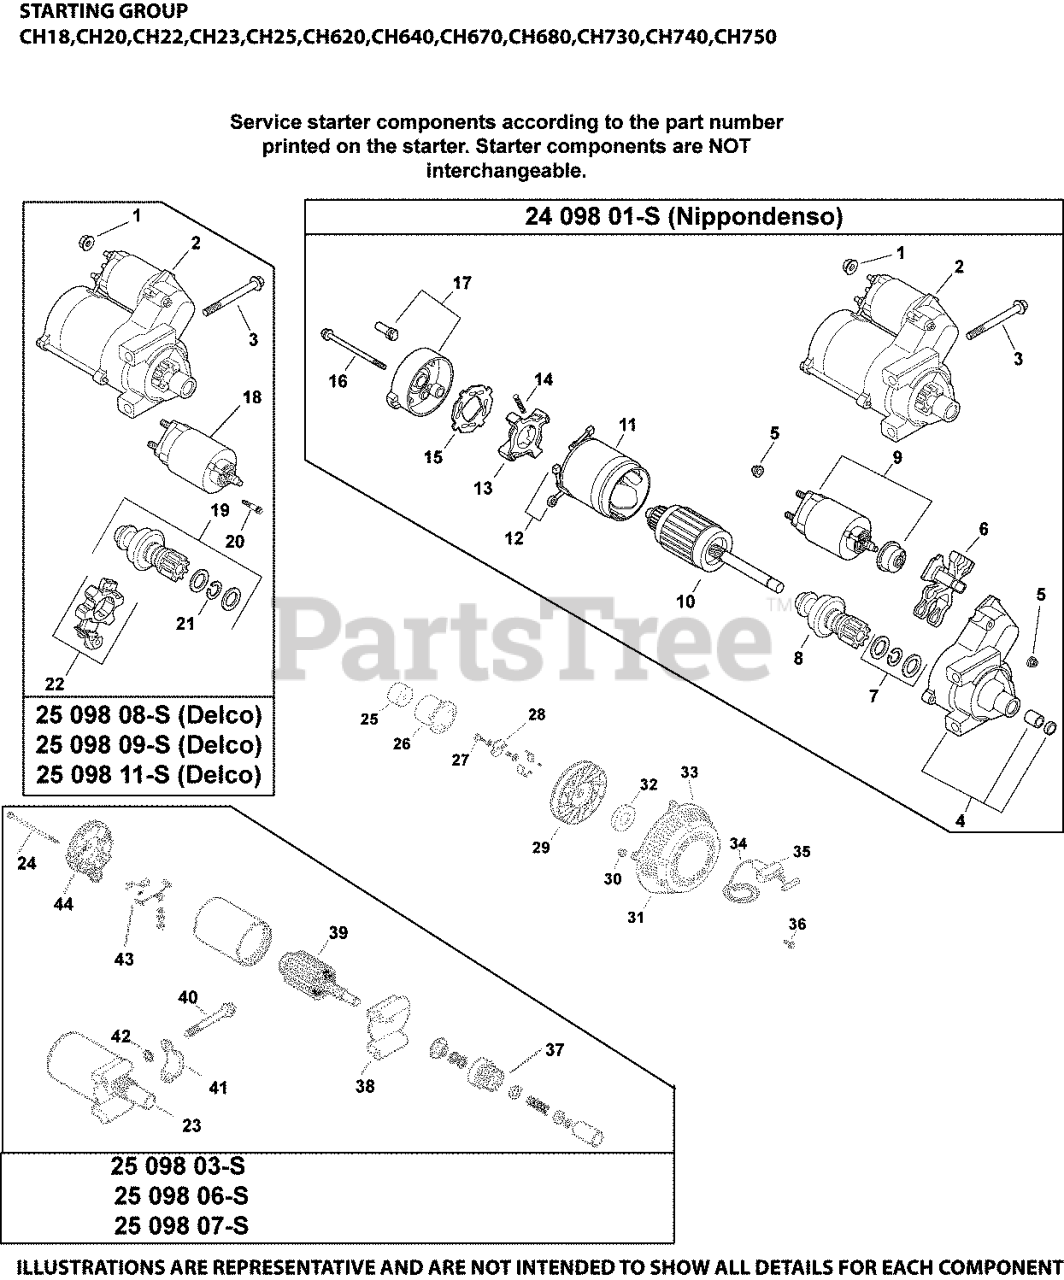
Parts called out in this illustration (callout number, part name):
1	NUT, FLG M8X1.25
2	ELECTRIC STARTER - SOLENOID SHIFT USE 25 098 20-s
3	SCREW, FLG M8X1.25X80
4	DRIVE, END CAP
5	NUT
6	LEVER, DRIVE
7	KIT, STARTER REPAIR
8	DRIVE PINION
9	SOLENOID
10	ARMATURE - (#DSC)
11	FRAME W/BRUSHES - DISCONTINUED
12	BRUSH & SPRING KIT
13	BRUSH HOLDER
14	SPRING, BRUSH
15	INSULATOR
16	THRU BOLT
17	COMMUTATOR, END CAP - DISCONTINUED
18	SOLENOID-(#DSC)
18	KIT, SOLENOID
19	KIT, STARTER PINION
20	SCREW, EXTERNAL TORX HEAD
21	RING, RETAINING-(#DSC)
22	KIT, BRUSH HOLDER
